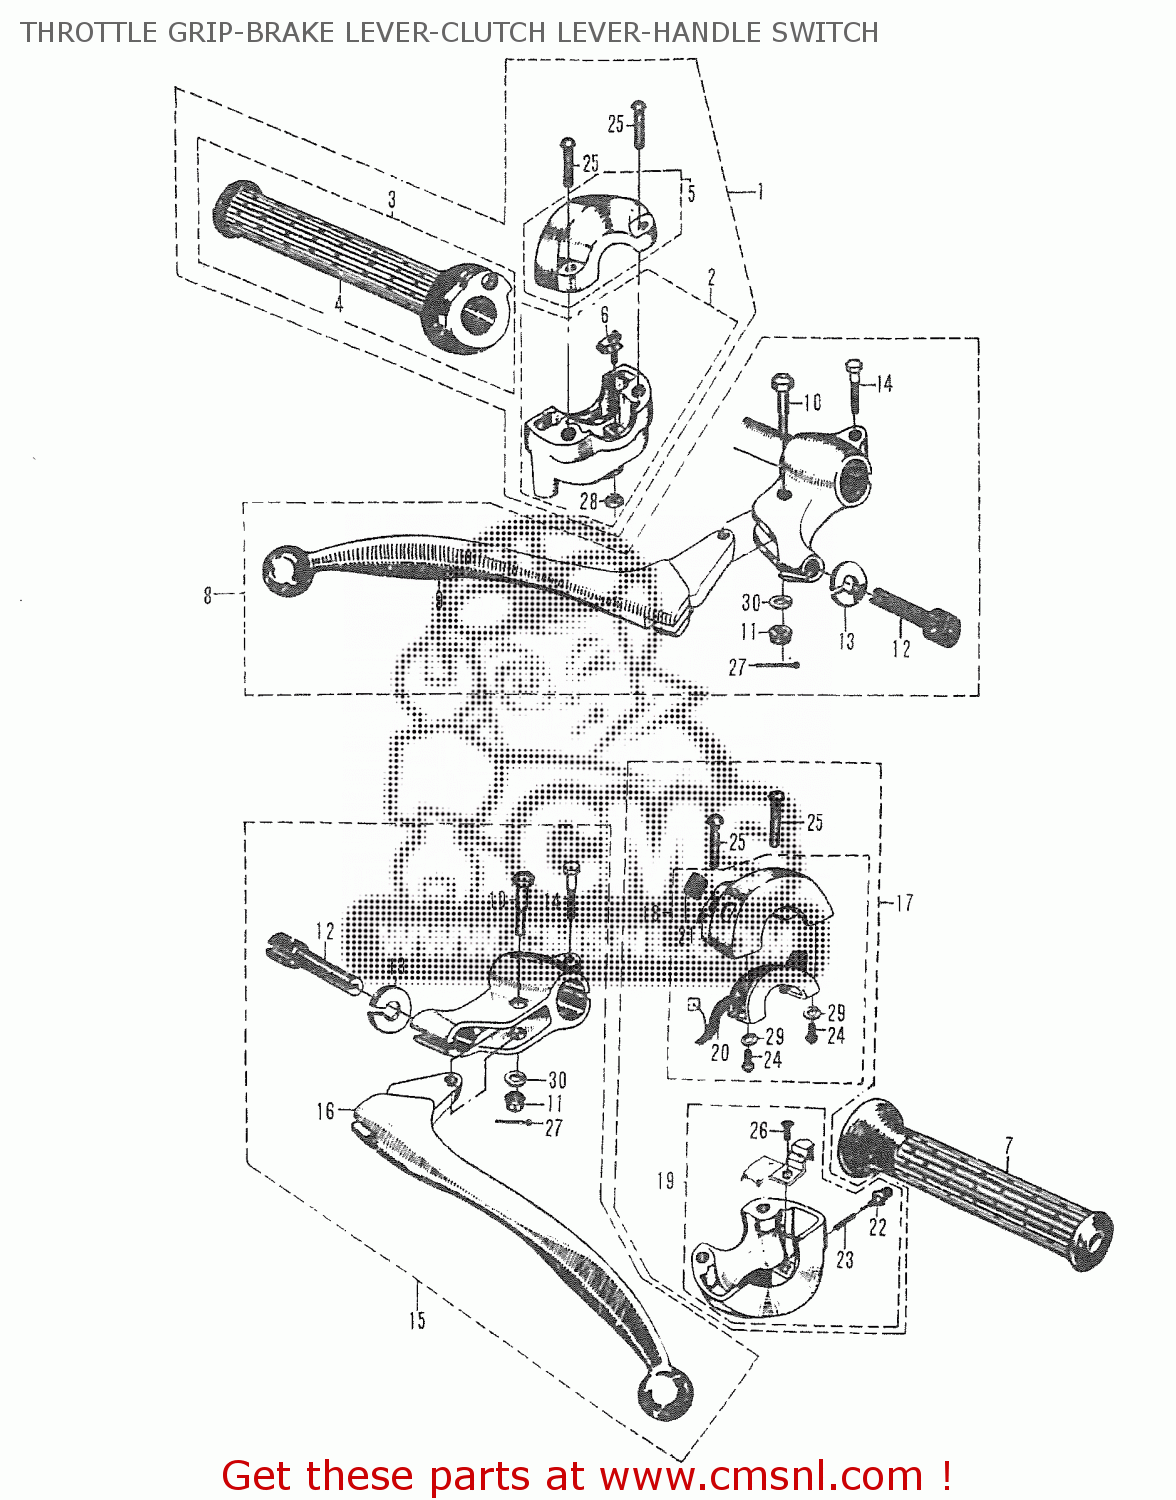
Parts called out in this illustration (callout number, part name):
1	THROTTLE GRIP ASS'Y
2	THROTTLE GRIP LOWER HOLDER ASS'Y
3	GRIP,THROTTLE
4	GRIP
5	THROTTLE GRIP UPPER HOLDER
6	THROTTLE GRIP ADJUSTER
7	GRIP,LEFT
8	LEVER ASSEMBLY,BRAKE
9	LEVER,BRAKE
10	BOLT,LEVER
11	NUT,LEVER FITTNG
12	ADJUSTER,CABLE
13	NUT,CABLE ADJUSTER
14	LEVER HOLDER FITTING BOLT
15	LEVER ASSEMBLY,CLUTCH
16	LEVER,CLUTCH
17	SWITCH ASSEMBLY,HANDLE
18	HANDLE SWITCH UPPER COVER ASS'Y
19	HANDLE SWITCH LOWER COVER ASS'Y
20	WIRING HARNESS, SWITCH
21	HANDLE SWITCH UPPER COVER RUBBER
22	BUTTON, HORN
23	HORN BUTTON SPRING
24	CROSS HEAD SCREW
25	CROSS HEAD SCREW
26	CROSS HEAD SCREW
27	COTTER PIN
28	HEXAGON NUT
29	LOCK WASHER
30	LOCK WASHER
